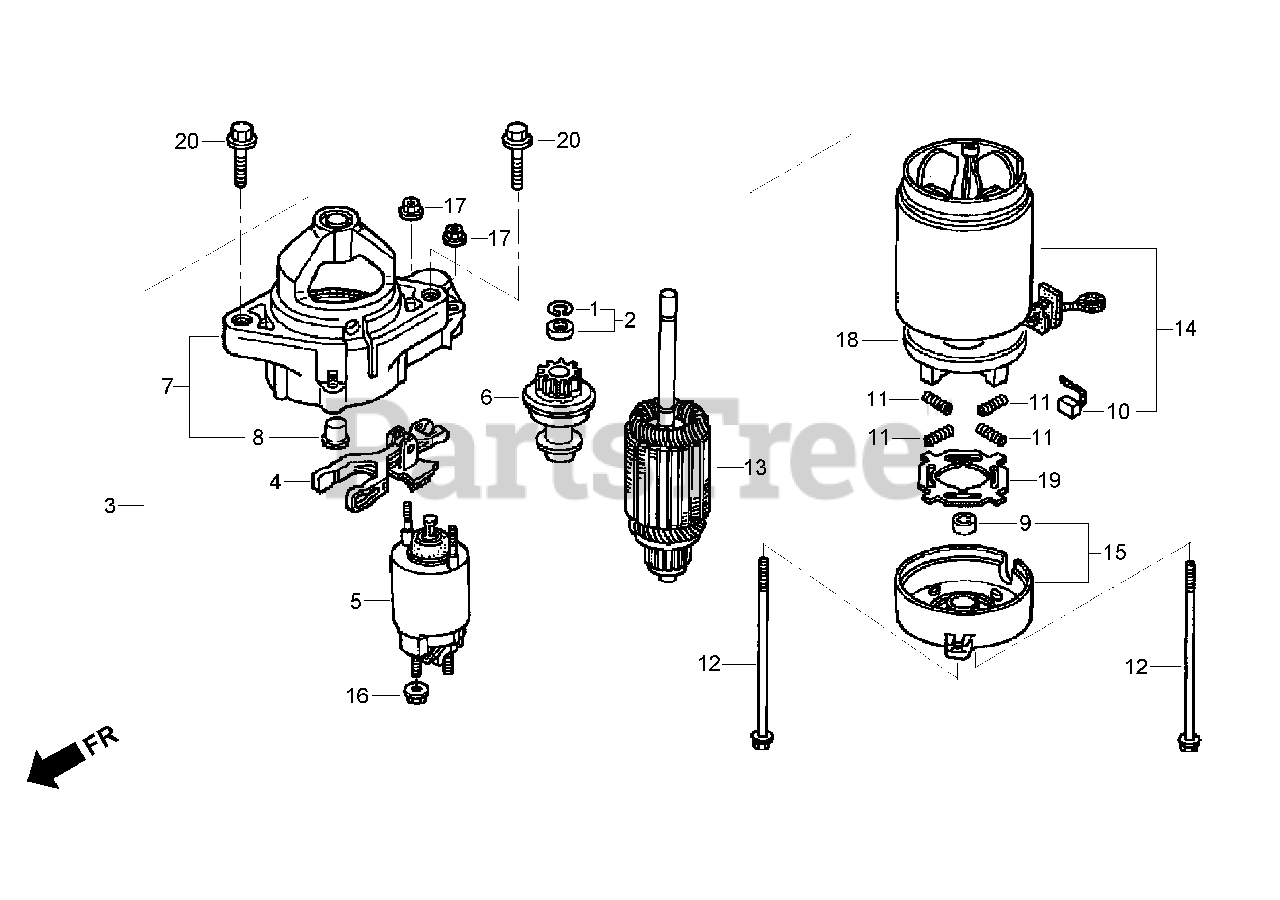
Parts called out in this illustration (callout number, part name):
1	RING-SNAP (DENSO)
2	CLUTCH STOP COLLAR SET
3	STARTER MOTOR ASM
4	LEVER-DRIVE, PINION
5	MAGNETIC SWITCH ASM
6	CLUTCH-OVERRUNNING
7	HOUSING-DRIVE SIDE
8	BEARING (A)
9	BEARING (B)
10	BRUSH
11	SPRING-BRUSH
12	BOLT-THROUGH
13	ARMATURE
14	YOKE
15	FRAME-END, COMMUTATOR
16	NUT-HEX (8MM)
17	NUT-FLANGE (5MM)
18	HOLDER-BRUSH
19	INSULATOR-HOLDER, BRUSH
20	BOLT-FLANGE (10X40)
